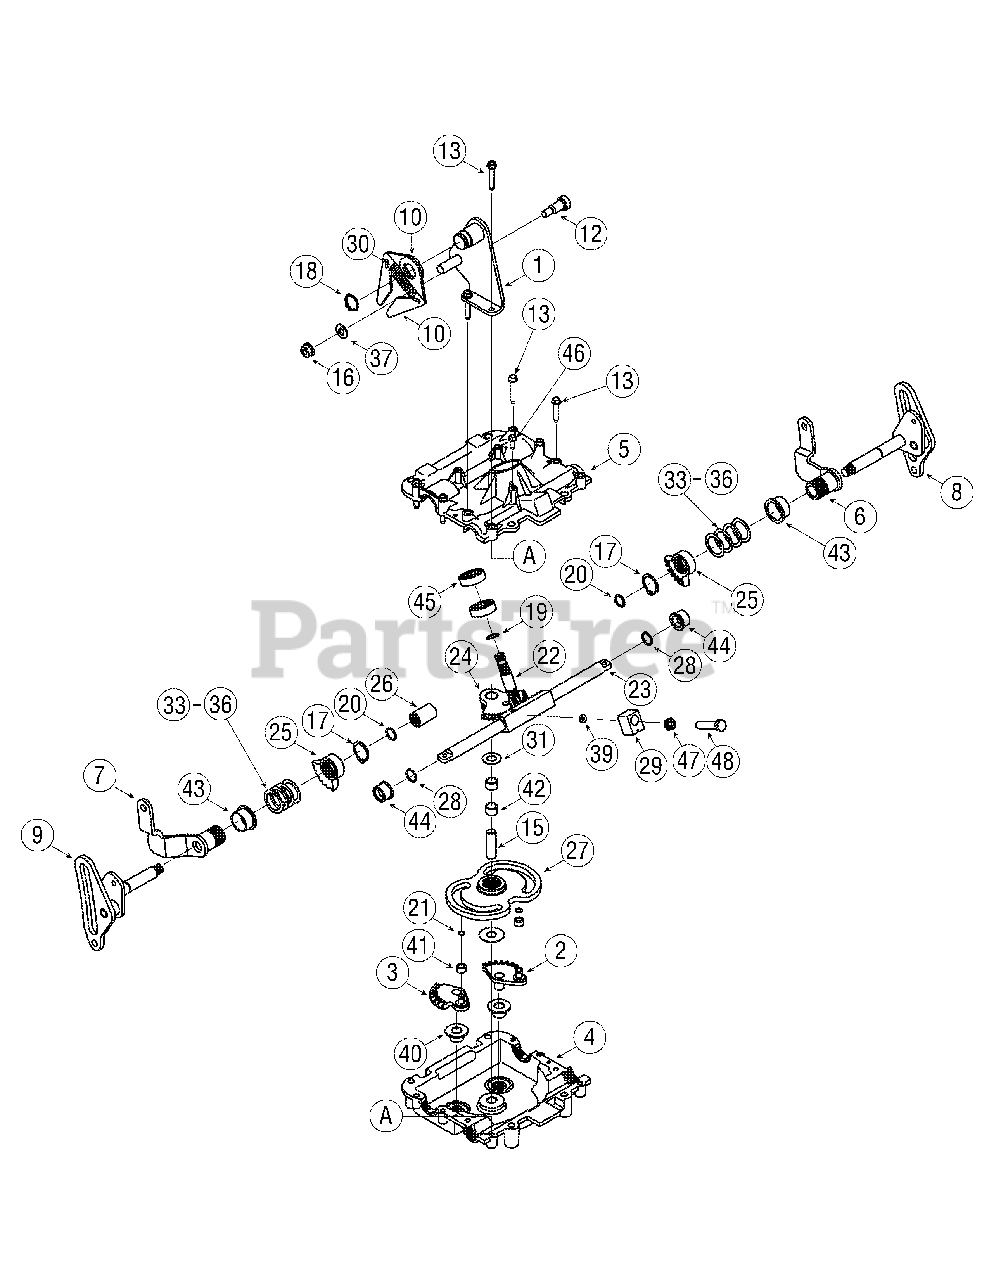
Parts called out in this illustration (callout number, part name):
1	Bracket, Steering Box Return
2	Gear, Bevel LH
3	Gear, Bevel RH
4	Housing, Steering Lower
5	Housing, Steering Upper
6	Arm, Hydro LH
7	Arm, Hydro RH
8	Cam, Hydro LH
9	Cam, Hydro RH
10	Arm, Neutral
11	Screw, Hex Wash Hd. Tapp, 1/4-20 x .5
12	Screw, Shoulder, .497 x .75 : 3/8-16
13	Screw, Hex Wash Hd. Tapp, 1/4-20 x 1.5
14	Screw, Hex Wash Hd. Tapp, 1/4-20 x 1.25
15	Shaft, Steering
16	Nut, Hex Flange Lock, 3/8-16 Gr5
17	Ring, Snap, 1.0 Dia. Shaft
18	Ring, External Retaining, .875 Shaft
19	Ring, Retaining, .56 Dia. Shaft
20	Ring, Retaining, .56 Dia. Shaft
21	Ring, Retaining, .31125 Dia. Shaft
22	Gear, Pinion, 7T
23	Gear, Synchro Rack
24	Gear, Steering, 17T
25	Gear, Steering, 26T
26	Tube, Coupler
27	Cam, Hydro Steering
28	O-Ring, .625 x .07
29	Bearing, Caster
30	Spring, Extension, .56 x 2.31 x .105
31	Washer, Flat, .508 x 1.0 x .02
32	Washer, Flat, .508 x 1.32 x .04
33	Washer, Flat, 1.015 x 1.375 x .005
34	Washer, Flat, 1.015 x 1.375 x .010
35	Washer, Flat, 1.015 x 1.375 x .015
36	Washer, Flat, 1.015 x 1.375 x .030
37	Washer, Thrust, .375 x .812 x .06
39	Washer, Flat, 188 x .437 x .042
40	Bearing, Flange, .5 x .7
41	Bearing, Sleeve, .437 x .3425
42	Bearing, Sleeve, .623 x .5025 x .25
43	Bearing, Sleeve, 1.2 x 1.0
44	Bearing, Flange, .625 x .875
45	Bearing, Ball, .5625 x 1.375 x .4375
46	Screw, TT: 1/4-20 x .750
47	Jam Nut, 3/8-24
48	Screw, HH Cap, 3/8-24 x 1.75
